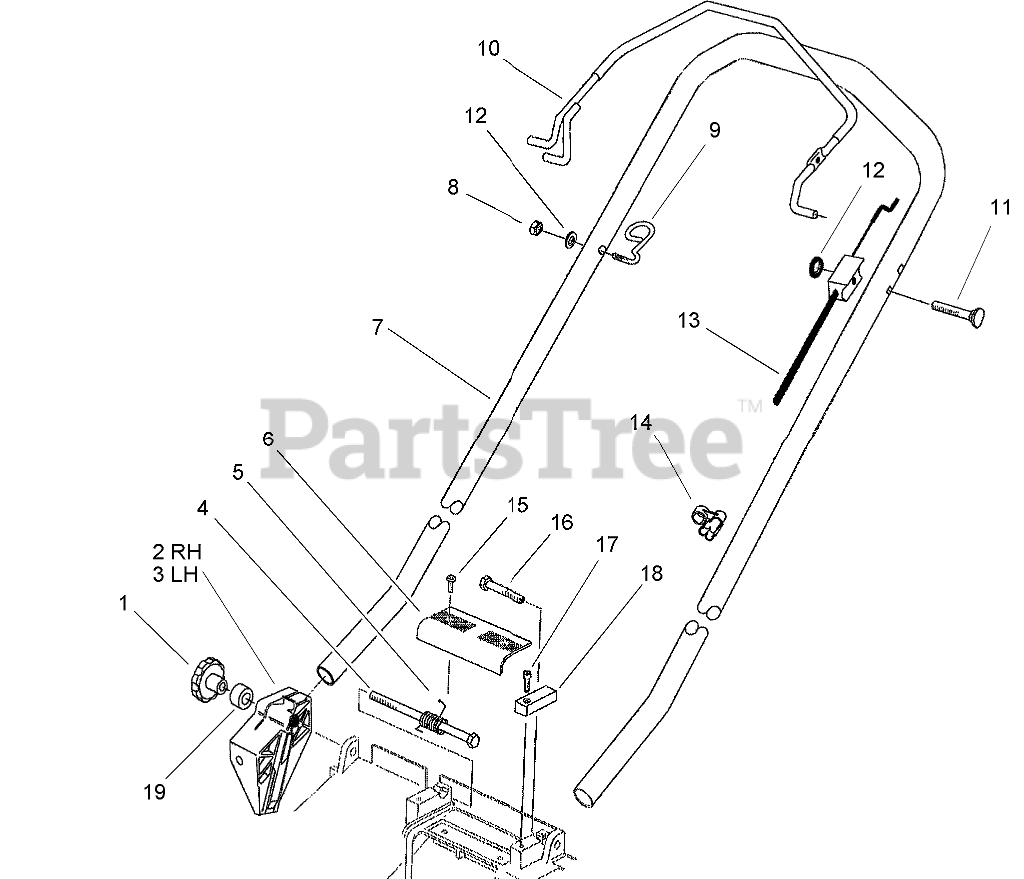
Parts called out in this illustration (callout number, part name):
2	MOUNT-HANDLE, RIGHT
3	MOUNT-HANDLE, LEFT
4	BOLT-LONG
5	SPRING-DOOR
6	GRIP-UPPER
7	HANDLE
8	NUT-LOCK, NI
9	GUIDE-ROPE
10	BAIL-BRAKE
12	WASHER-FLAT
13	CABLE-BRAKE
14	CLAMP-CABLE
15	SCREW-PPH, PLASTITE
16	BOLT-SHORT
17	SCREW-CAP, HINGE
18	CAP-BOLT
19	SPACER-MOUNT, HANDLE
